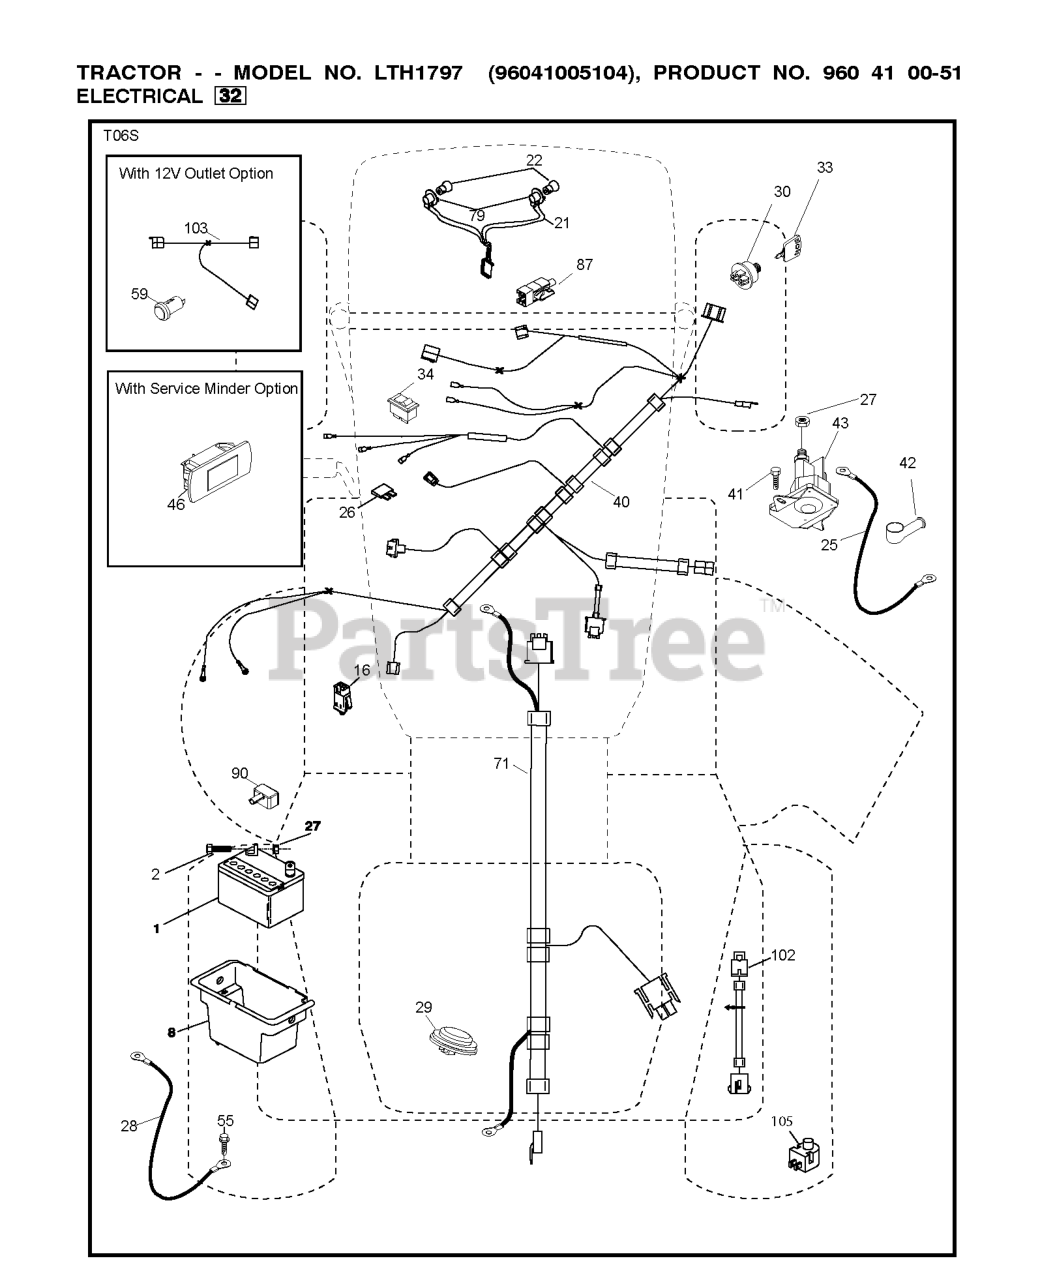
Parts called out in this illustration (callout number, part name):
1	Battery 12 Volt 25 Amp
2	BOLT.HEX.1/4.X.3/4.DICHROMATE
8	BOX.BATTERY.MNT.REAR.L
16	SWITCH INTERLOOK PUSH-IN
21	HARNESS.LIGHT W/4152J BULBS
25	CABLE.STARTER.6GA.BL/RED.14.
26	FUSE 20AMP
27	NUT
28	CABLE.BLACK.18"REAR.BA
29	SWITCH.SEAT.DELTA.OPC.
30	SWITCH.IGN.DELTA.W.LGH.ROS
33	KEY.CHAIN.BLISTER.PACK.GEN.USA
40	HARNESS IGN. DASH
41	SCREW
42	TERMINAL COVER
43	SOLENOID.W/BRASS.PLUNGER
46	RP.GUAGE.SRVCMNDR.HRMTR.
55	SCREW 5/16"
71	HARNESS.IGN.CHASS.TEX.REAR.BAT
79	BULB HOLDER ASM.
87	SWITCH.INTRLCK.CLUTCH.
90	COVER, TERMINAL BATTERY
102	HARNESS PIGTAIL PCH TEX ROS
105	REVERSE SWITCH
